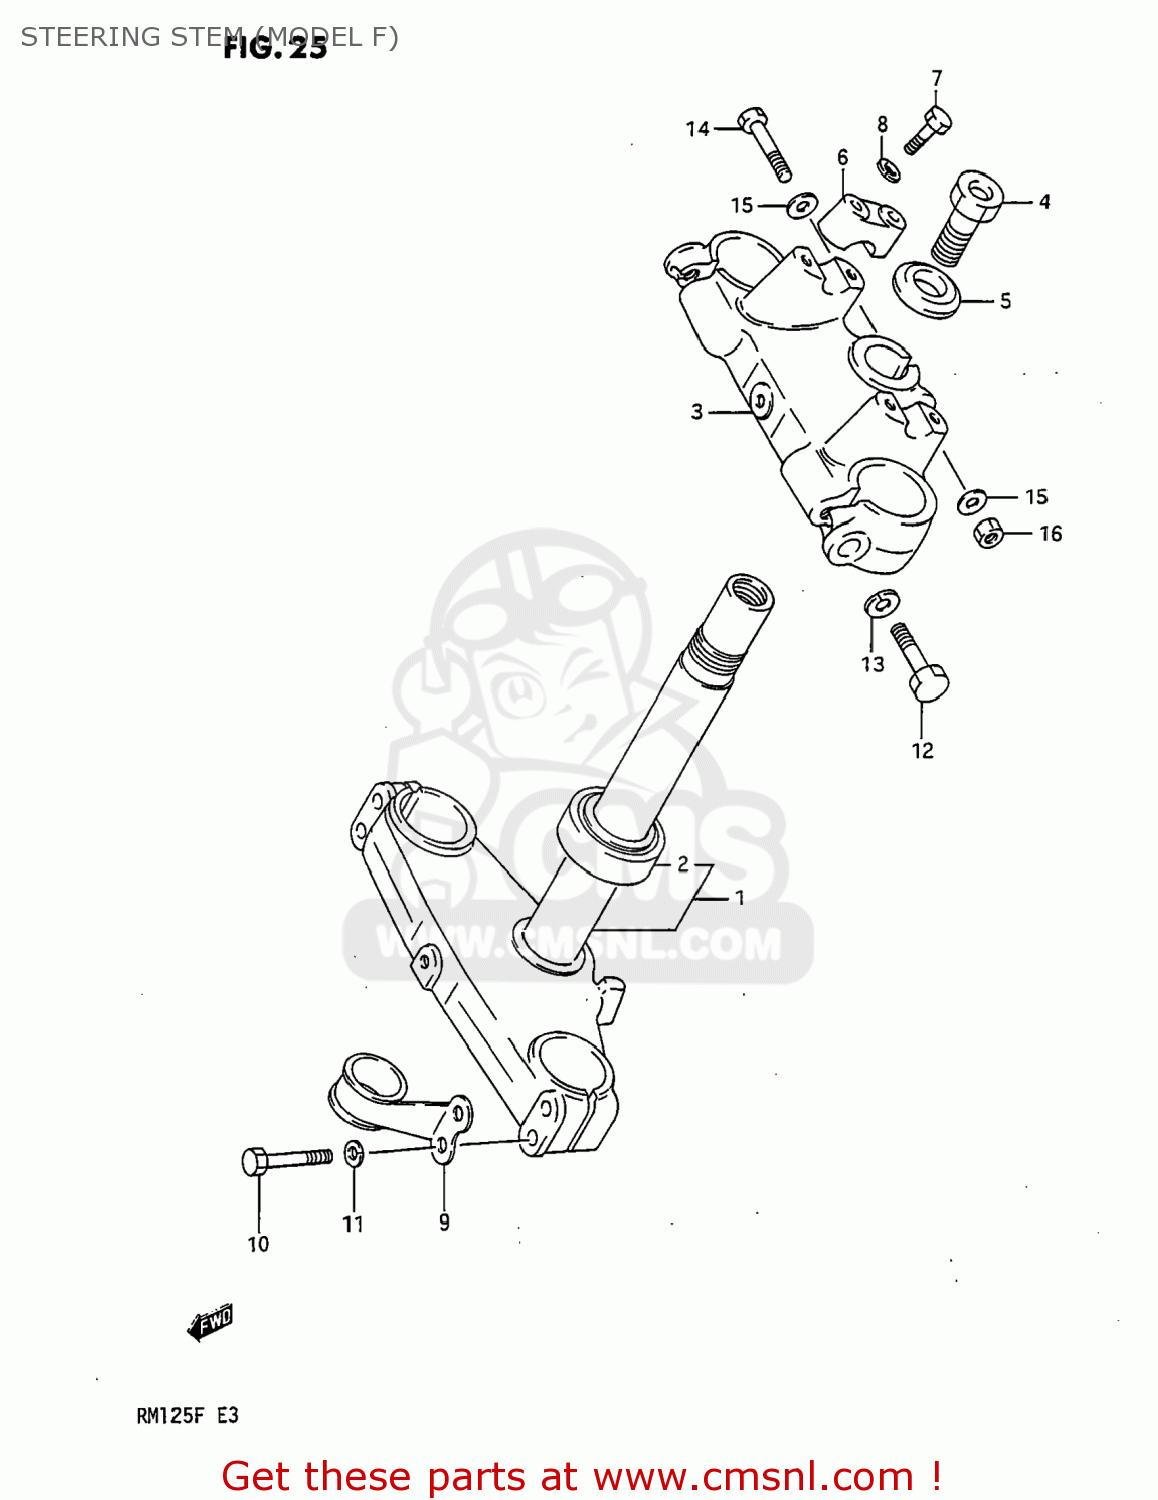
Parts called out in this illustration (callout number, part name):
1	STEM,STEERING
2	BEARING
3	HEAD,STEERING STEM
4	BOLT
5	WASHER
6	HOLDER,HANDLEBAR
7	BOLT
8	WASHER,LOCK,8.
9	GUIDE,CABLE
10	BOLT 8X40
11	WASHER,LOCK,8.
12	BOLT
13	LOCK WASHER
14	BOLT 8X50
15	WASHER
16	NUT
